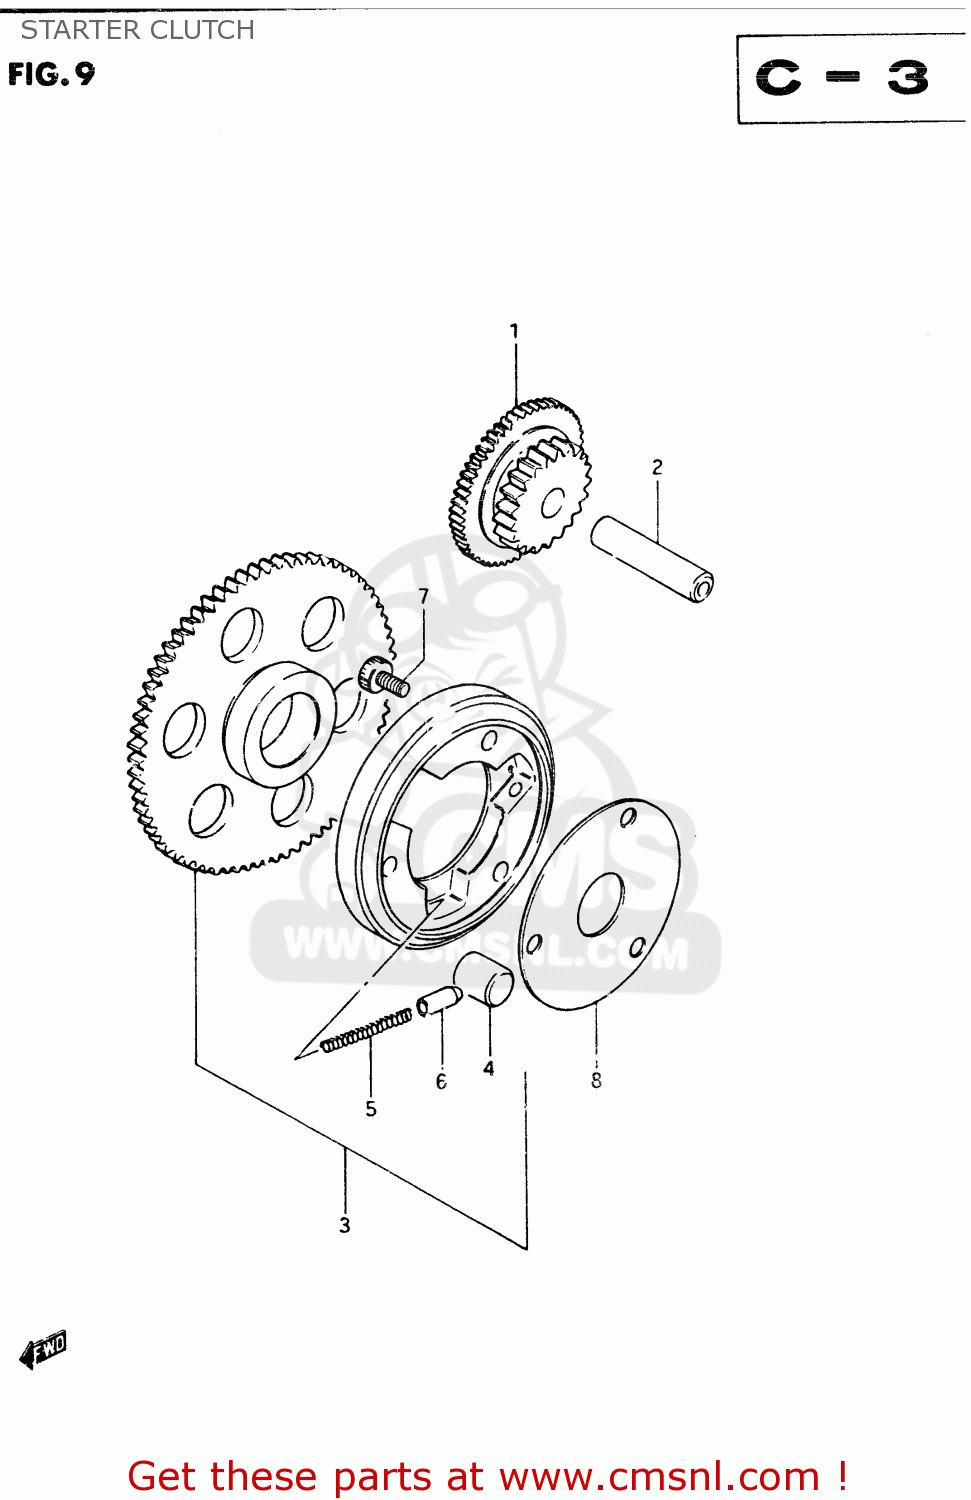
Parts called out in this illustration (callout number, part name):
1	GEAR,STARTER IDLE
2	PIN(7.4X13X56)
3	CLUTCH SET,STARTER
4	ROLLER(15X13)
5	SPRING
6	PIECE,PUSH
7	BOLT
8	SHIM,STARTER CLUTCH HUB
